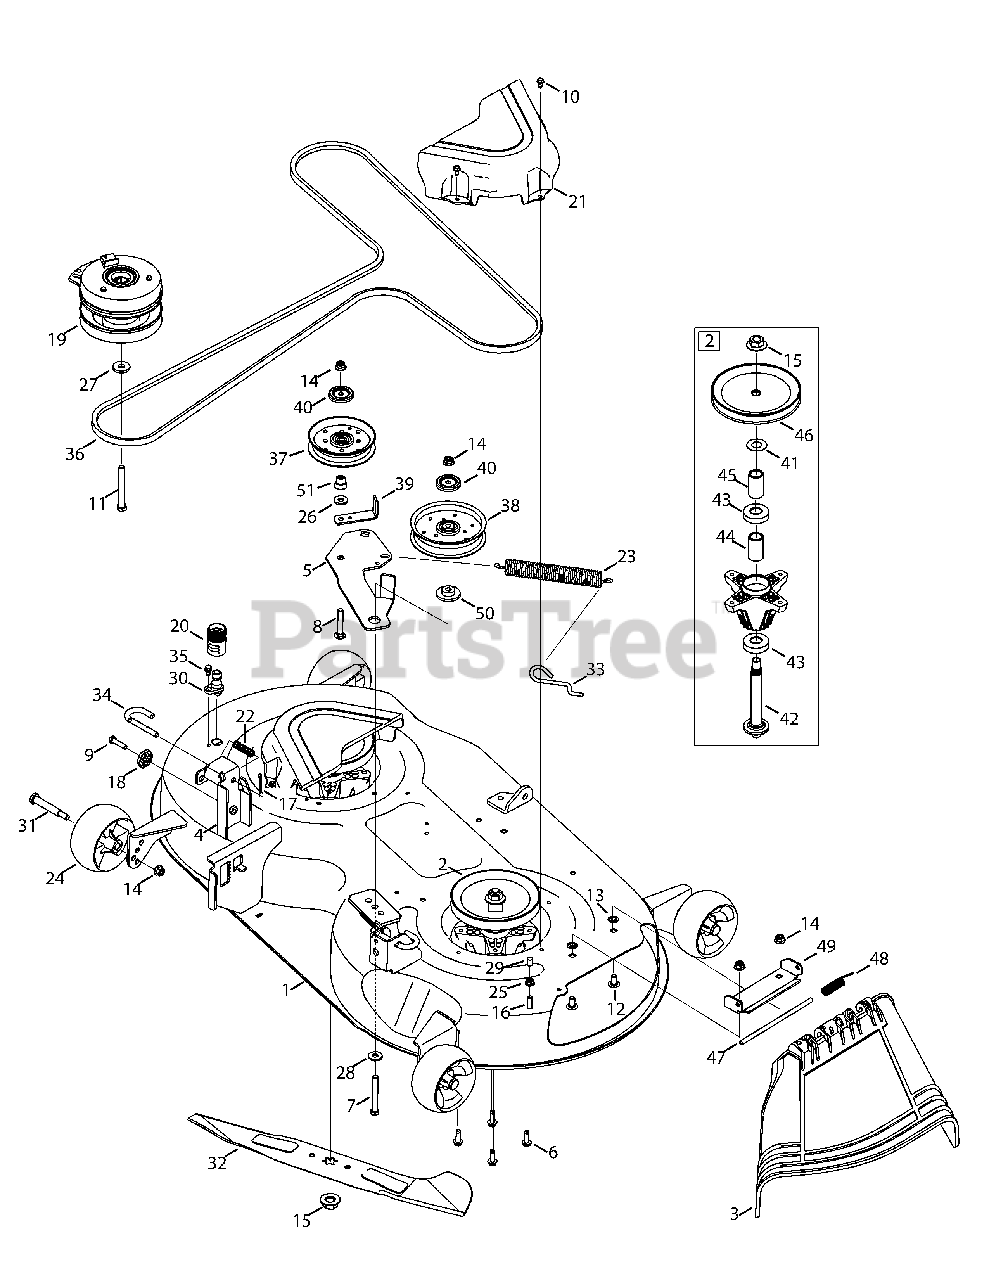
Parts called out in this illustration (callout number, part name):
1	46" Deck
2	Spindle Assembly
3	Chute Deflector Assembly
4	Deck Lift Bracket
5	Idler Bracket
6	Hex Washer Screw, 5/16-18 x .750
7	Hex Cap Screw, 3/8-16 x 3.50
8	Carriage Screw, 3/8-16 x 1.75
9	Hex Cap Screw, 5/16-18 x 1.25
10	Hex Washer Screw, 1/4-20 x .625
11	Screw, 7/16-20 x 3.25
12	Carriage Screw, 3/8-16 x .75
13	Push Nut, 3/8
14	Flange Lock Nut, 3/8-16
15	Hex Flange Nut, 5/8-18
16	Hex Cap Screw, 5/16-18 x 1.00
17	Cotter Pin, 5/32 x 1.25
18	Deck Adjustment Gear
19	Electric PTO Clutch
20	Water Nozzle Adapter
21	Belt Cover
22	Compression Spring, .66 x 1.9
23	Extension Spring, 1.25 OD x 1.751
24	Deck Ball Wheel, 5.0
25	Flange Lock Nut, 5/16-18
26	Flat Washer, .385 x .870 x .092
27	Flat Washer, .450 x 1.25 x .164
28	Flat Washer, .406 x 1.00 x .105
29	Cap, .290 x .500
30	Deck Wash Nozzle
31	Shoulder Screw, .5 x 2.5 x 3/8-16
32	Blade, 2 in 1, 23.25
33	Deck Spring Rod
34	Deck Hanger Rod
35	Shoulder Screw, .500 x 1/4-20
36	V-Belt
37	Idler Pulley, 4.25 Dia.
38	Idler Pulley, 5.00 Dia.
39	Bracket Belt Guard
40	Pulley Cap
41	Washer, .760 x 1.50 x .030
42	Spindle Shaft
43	Ball Bearing
44	Spacer, .792 x 1.060 x 1.860
45	Spacer, .8 x 1.1 x 2.26
46	Deck Pulley
47	Hinge Pin
48	Torsion Spring
49	Chute Bracket
50	Shoulder Spacer
51	Shoulder Spacer
